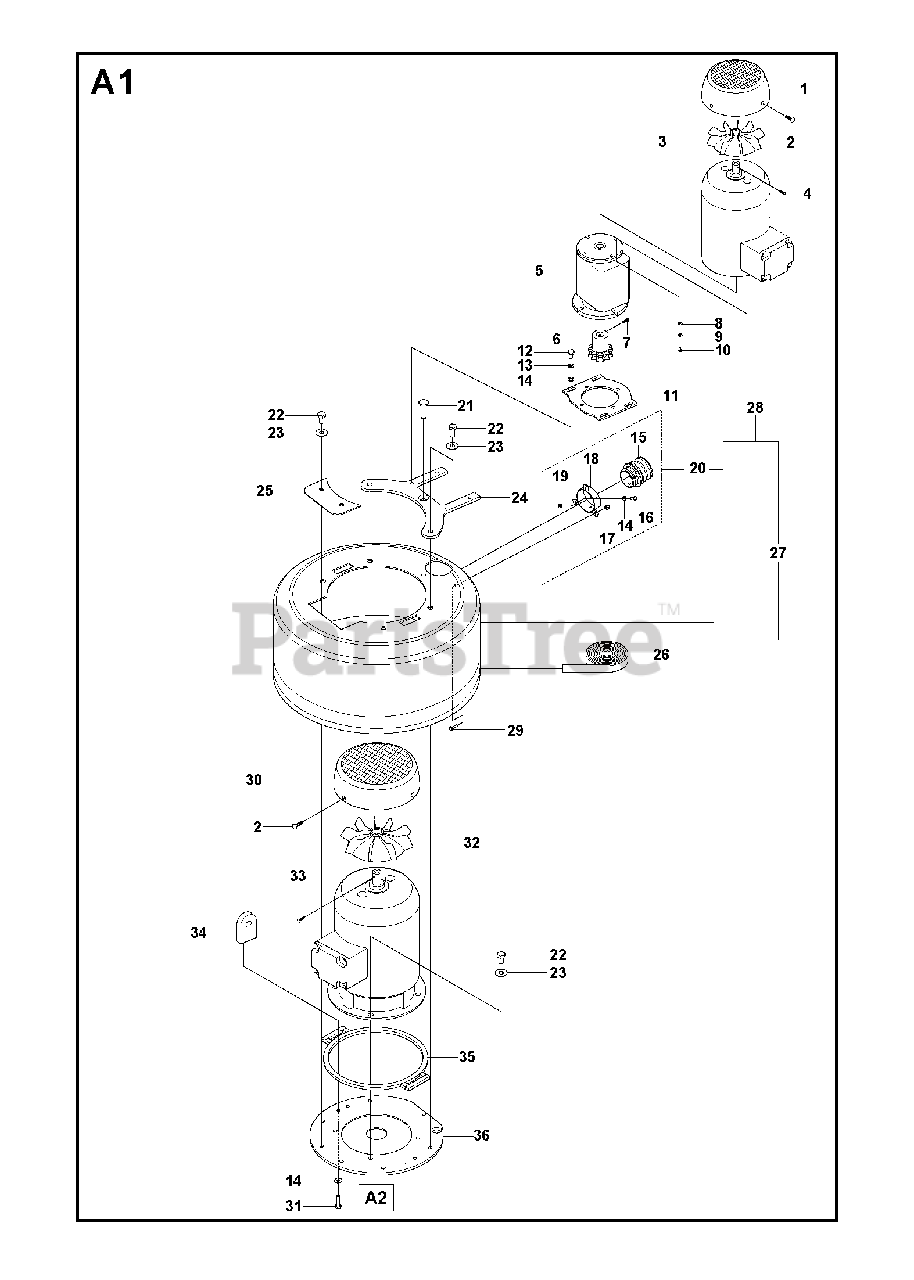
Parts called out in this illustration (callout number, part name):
12	SCREW EHHM
13	SPRING WASHER
14	WASHER
17	HEXAGON LOCKING NUT
19	HEXAGON LOCKING NUT
23	WASHER
29	SCREW CRCSFM
